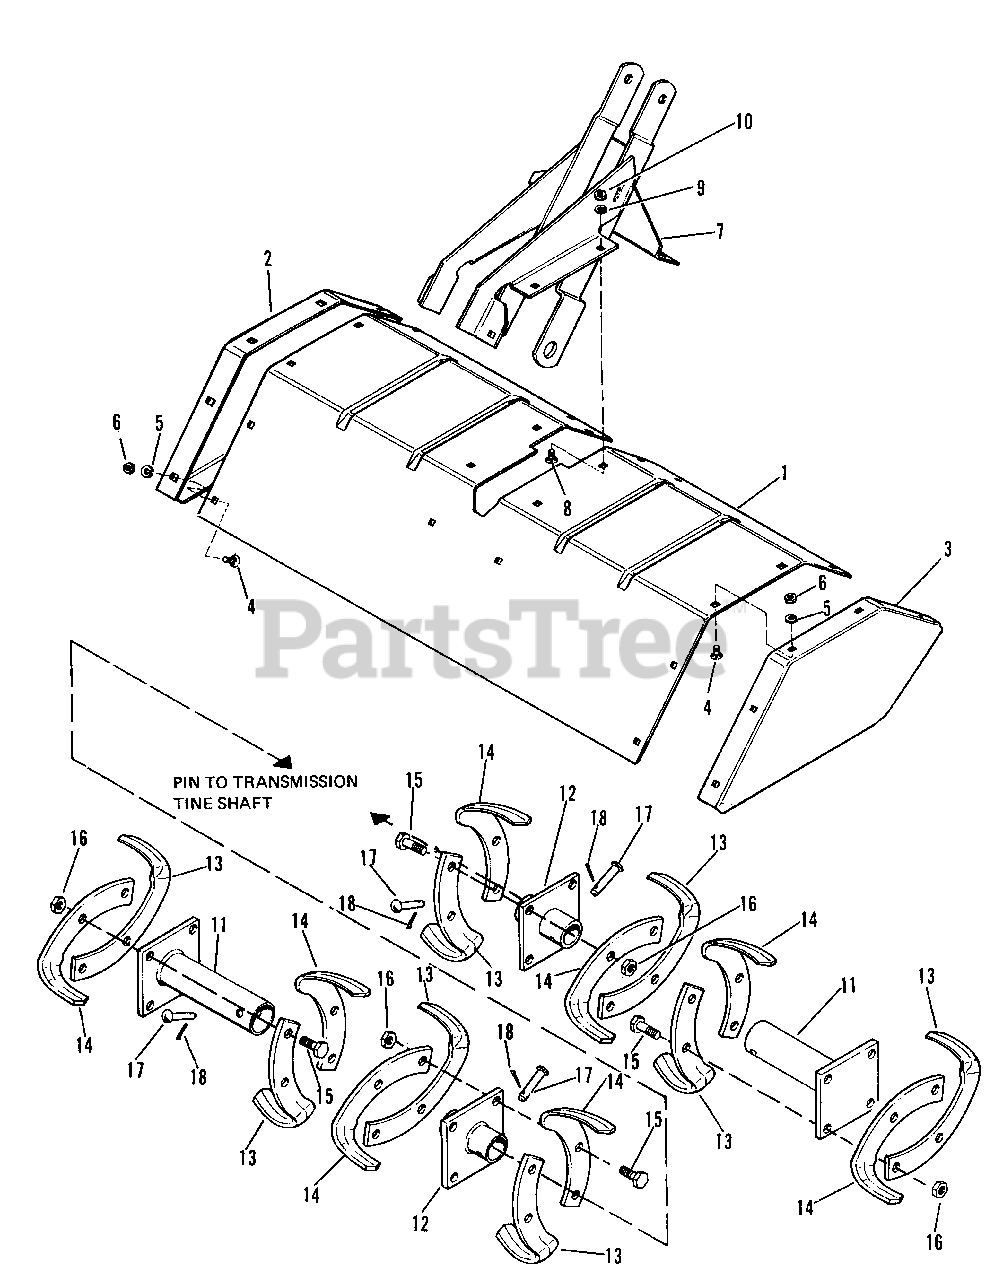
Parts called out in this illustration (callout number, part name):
1	Deflector
2	End Plate Deflector L.H.
3	End Plate Deflector R.H.
4	Bolt Carriage, 5/16"-18 x 1/2"
5	Lock Washer, 5/16"
6	Full Hex. Nut, 5/16"-18
7	Support Assembly
8	Bolt Carriage, 5/16"-18 x 3/4"
9	Lock Washer, 5/16"
10	Full Hex. Nut, 5/16"-18
11	Tine Hub Assembly
12	Inner Tine Plate Assembly
13	Tine Blade L.H.
14	Tine Blade R.H.
15	Hex Cap Screw, 7/16"-20 x 1-1/4" lg.
16	Full Hex. Lock Nut, 7/16"-20
17	Pin
18	Cotter Pin, 1/8" x 3/4"
